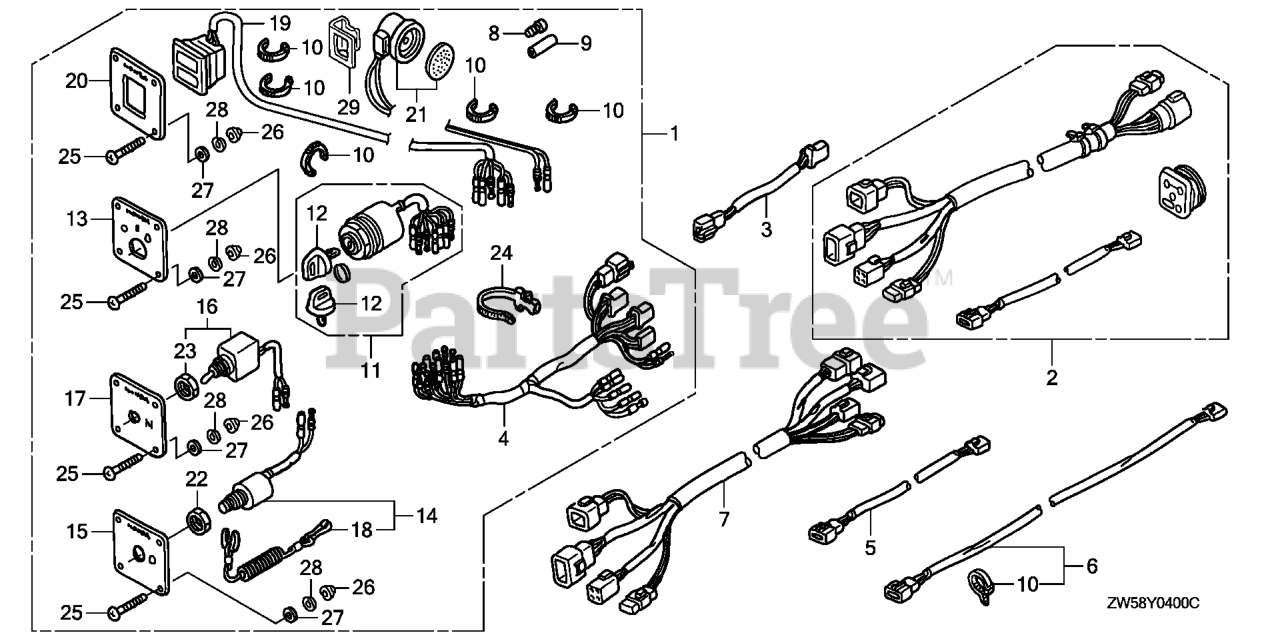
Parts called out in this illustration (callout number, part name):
1	PANEL KIT, CONTROL (B)
2	CABLE KIT, SWITCH INDICATOR
3	SUB-HARNESS ASSY., POWER TRIM-TILT (A)
4	HARNESS ASSY., SWITCH PANEL
5	CABLE ASSY., EXTENSION (3P 7FT) (FOR 2-LED)
6	CABLE ASSY., EXTENSION (3P 30FT) (FOR 2-LED)
7	CABLE ASSY., EXTENSION (17P 7FT)
8	PLUG, CONNECTOR (INNER) (TROLLING CONTROL)
9	PLUG, CONNECTOR (OUTER) (ENGINE NO.)
10	TIE, CABLE (NATURAL 2.4X92) Use up to Frame SN 1300359.
11	SWITCH ASSY., COMBINATION DUAL QTY = (2) (SINGLE)
12	KEY ASSY., COMBINATION SWITCH (35100-ZV5-003 ONLY) DUAL QTY = (4) (SINGLE)
13	PANEL, SWITCH
14	SWITCH ASSY., EMERGENCY STOP
15	PANEL, EMERGENCY STOP SWITCH
16	SWITCH ASSY., SOLENOID
17	PANEL, SOLENOID
18	WIRE, EMERGENCY (SINGLE) (DUAL)
19	LAMP ASSY., INDICATOR (2-LED)
20	PANEL, INDICATOR
21	BUZZER, WARNING
22	NUT, HEX. (16MM) DUAL QTY = (2) (SINGLE)
23	NUT, HEX. (12MM)
24	BAND, WIRE HARNESS (150MM) (NATURAL) DUAL QTY = (2) (SINGLE)
25	SCREW, PAN (5X40) DUAL QTY = (8) (SINGLE)
26	NUT, FLANGE (5MM) DUAL QTY = (8) (SINGLE)
27	WASHER, PLAIN (5MM) DUAL QTY = (8) (SINGLE)
28	WASHER, SPRING (5MM) DUAL QTY = (8) (SINGLE)
29	BRACKET, BUZZER
